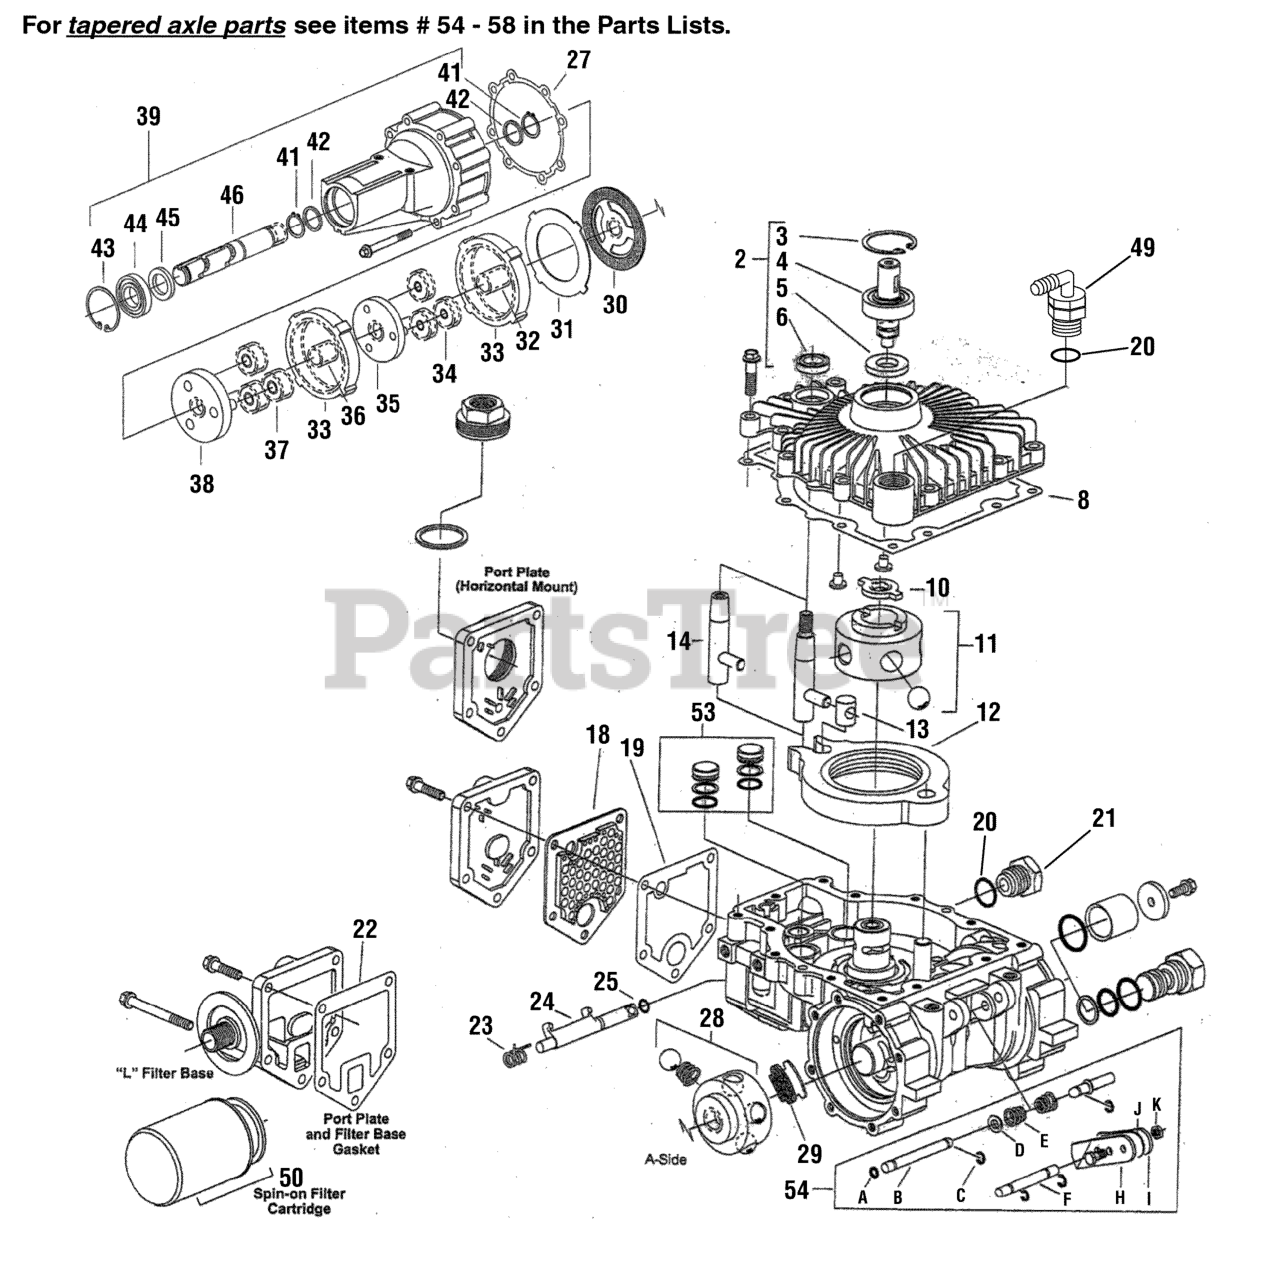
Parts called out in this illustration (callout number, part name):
2	COVER (ONLY)
3	RETAINING RING (101680-156)
4	INPUT SHAFT W/BRG. (106073)
5	SEAL (93955)
6	SEAL (93895)
8	GASKET (105327)
10	DRIVE (104107)
11	MOTOR ROTOR BALL ASSY (105228)
12	CAM RING (105813)
13	INSERT (103621)
14	CONTROL SHAFT (104935)
18	FILTER (106202)
19	GASKET (106200)
20	O-RING (8785-010)
21	DUMP VALVE NUT (104664)
22	GASKET (104392)
23	SPRING (104684)
24	DUMP VALVE BRACKET (105660)
25	O-RING (8761-013)
27	GASKET (106129)
28	MOTOR ROTOR BALL ASSEMBLY (104551)
29	FRICTION PAD (106054)
30	REACTION PLATE (106414)
31	BACK-UP PLATE (106104)
32	GEAR (104338)
33	GEAR RING (106027)
34	GEAR, 21T PLANET, FIRST (106167)
35	CARRIER (106174)
36	GEAR (104812)
37	GEAR (106169)
38	SECONDARY CARRIER (106137)
39	AXLE HOUSING ASSEMBLY (107001-001)
41	SNAP RING (103983-098)
42	THRUST WASHER (103966)
43	RETAINING RING (101680-206)
44	BEARING (104928)
45	AXLE SEAL (103960)
46	STRAIGHT AXLE SHAFT (771) 106177-000
49	90 DEGREE FITTING (105636)
50	OIL FILTER (103144-000)
53	PISTON (104294-000)
54A	QUAD SEAL (106450)
54B	PUSH ROD (106079)
54C	E-CLIP (106437-000)
54D	GASKET (106784)
54E	CONICAL SPRING (106078)
54F	BRAKE SHAFT ()106216-000
54H	RIGHT BRAKE LEVER (106128-001)
54I	LEFT BRAKE LEVER (106128-002)
54J	SHIM KIT (106144-XXX)
54K	NUT, HEX LOCK (16188-4)
